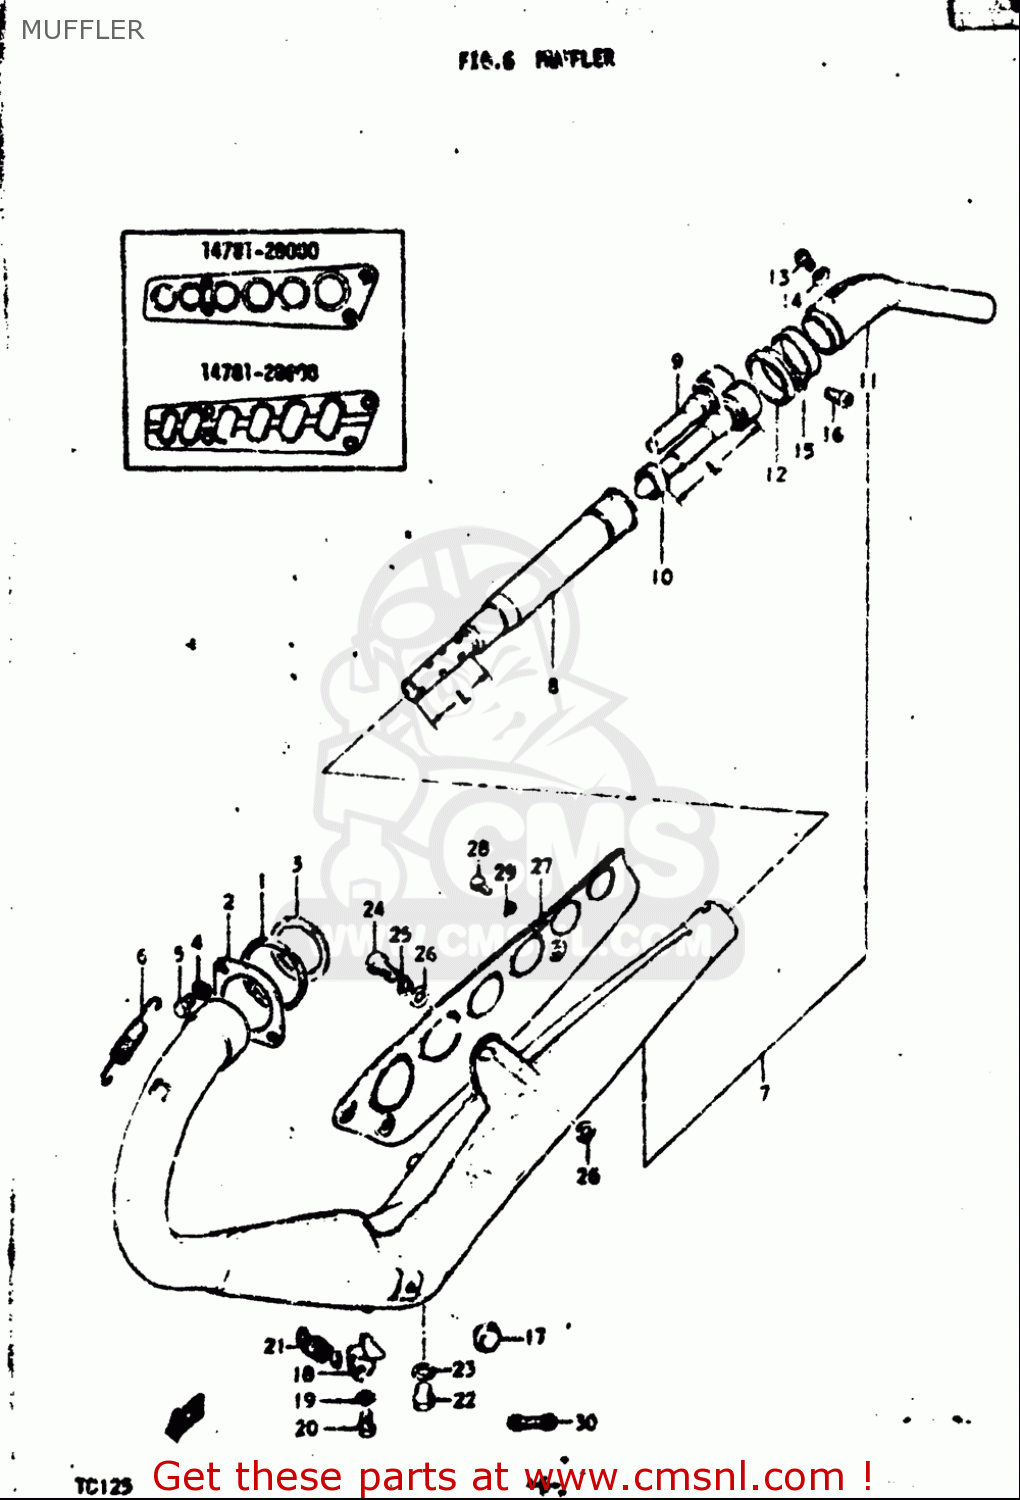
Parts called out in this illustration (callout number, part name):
1	GASKET,EXHAUST PIPE (NAS)
2	CLAMP,EXHAUST PIPE
3	CUSHION,EXHAUST PIPE
4	WASHER,LOCK
5	BOLT
6	SPRING
10	TUBE,MUFFLER CLEAN OUT
12	GASKET,MUFFLER TAIL PIPE (NAS)
13	SCREW
15	CLAMP
16	SCREW
17	CUSHION(11.5X22X20)
18	BRACKET, MUFFLER STOPPER
19	WASHER,LOCK
20	BOLT
21	SPRING
22	BOLT 10X9
23	GASKET(10X14X3.6) (NAS)
24	BOLT
25	WASHER,LOCK
26	WASHER
28	SCREW
29	WASHER,LOCK
30	CLAMP
